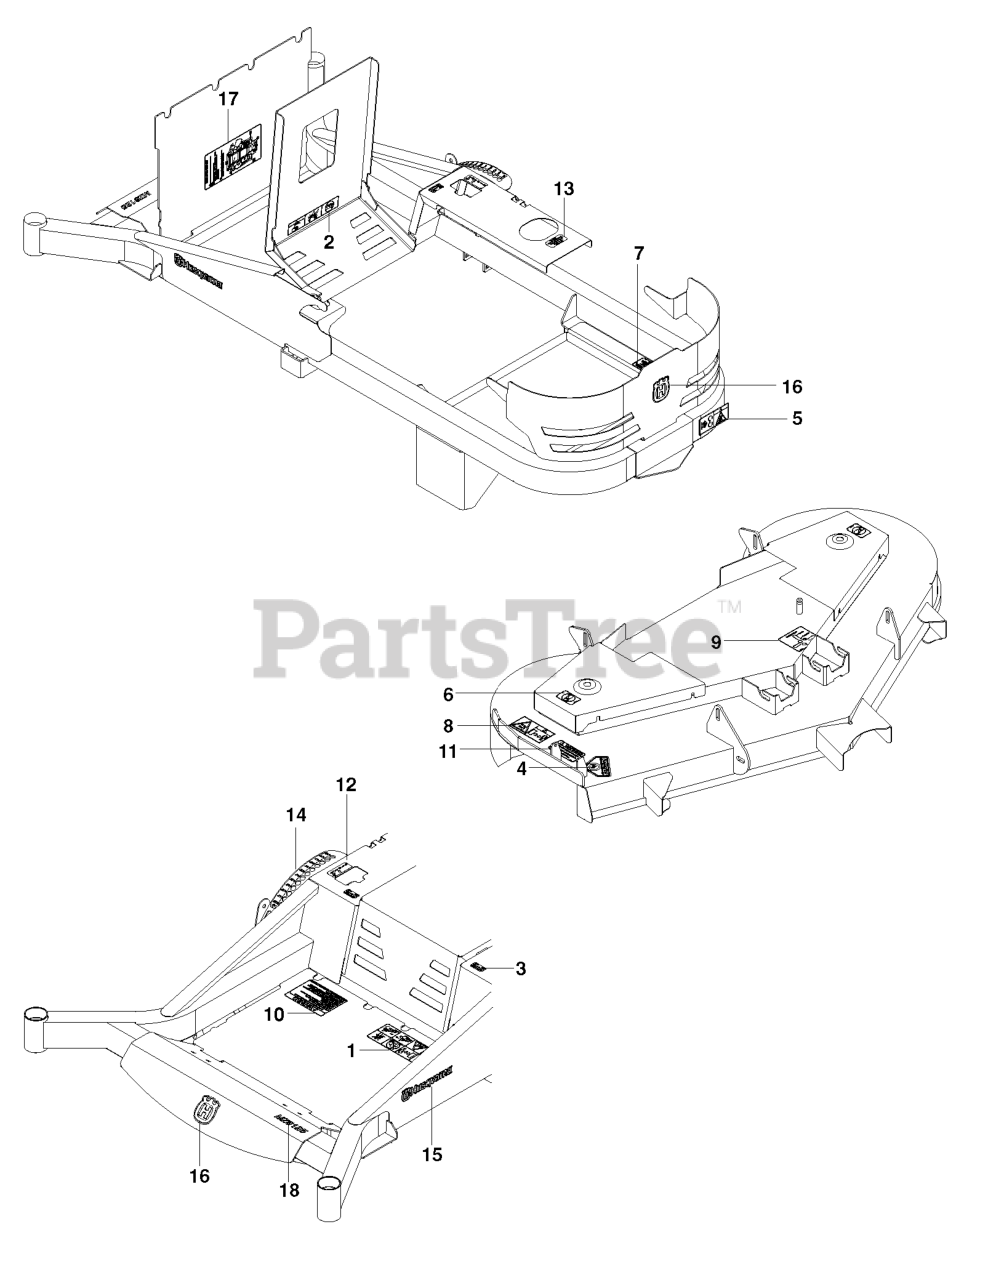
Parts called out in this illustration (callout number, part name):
1	DECAL, WARNING
2	EURO DECAL-BATTERY WARNIN6
3	DECAL, MOTION CONTROL
4	DECAL, CPSC
5	DECAL, BELT DRIVE
6	DECAL, NO STEP
7	DECAL, PROP. 65
8	DECAL, EURO SEVERING
9	RP DECAL, BELT ROUTING
10	DECAL, WARNING
11	DECAL, CAUTION
12	DECAL, F.S.T.
13	DECAL, OIL TANK
14	DECAL, HEIGHT ADJUST
15	DECAL.HOOD.LOGO.ORANGE.HUSQVAR
16	DECAL, CROWN H 70MM
17	DECAL, SERVICE
18	DECAL, MZ5226
